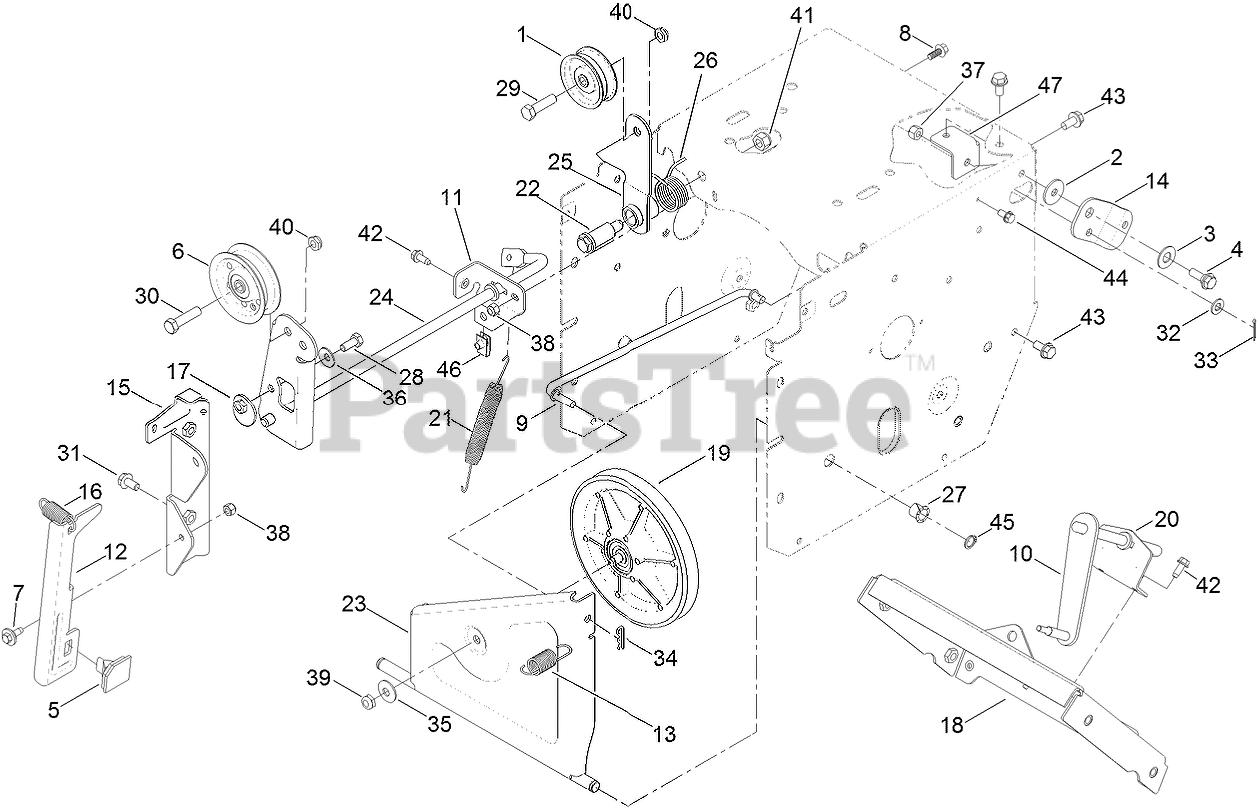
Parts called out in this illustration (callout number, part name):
1	PULLEY-IDLER
2	WASHER-PIVOT
3	WASHER
4	SCREW-SHOULDER
5	PAD-BRAKE
6	PULLEY-IDLER
7	SCREW-SHOULDER
8	SCREW-HHF
9	LINK-CONTROL, SPEED
10	LEVER-CONTROL, TRACTION
11	BRACKET-CLUTCH, IMPELLER
12	ARM-BRAKE
13	SPRING-EXTENSION
14	BELLCRANK-DRIVE
15	BRACKET-IDLER, IMPELLER
16	SPRING-EXTENSION
18	SHIFT PLATE ASM
19	PULLEY-TRACTION
20	BRACKET-ROD, SHIFT
21	SPRING-EXTENSION
22	BOLT-SHOULDER
23	BRACKET-WHEEL, FRICTION
24	IMPELLER CLUTCH ASM
25	ARM-IDLER, TRACTION
26	SPRING-TORSION
27	BUSHING-NYLINER
28	SCREW-HH
29	SCREW-HH
30	SCREW-HH
31	SCREW-HHF
32	WASHER-PLAIN
33	PIN-COTTER
34	PIN-COTTER
35	WASHER-BELLEVILLE
36	WASHER-BELLEVILLE
37	NUT-LOCK, NI
38	NUT-LOCK, NI
39	NUT-HEX
40	NUT-LOCK, NI
41	NUT-LOCK, NI
42	SCREW-HWH
43	SCREW-HWHTF
44	SCREW-HWH
45	RING-RETAINING
47	BRACKET-FRAME, LH
